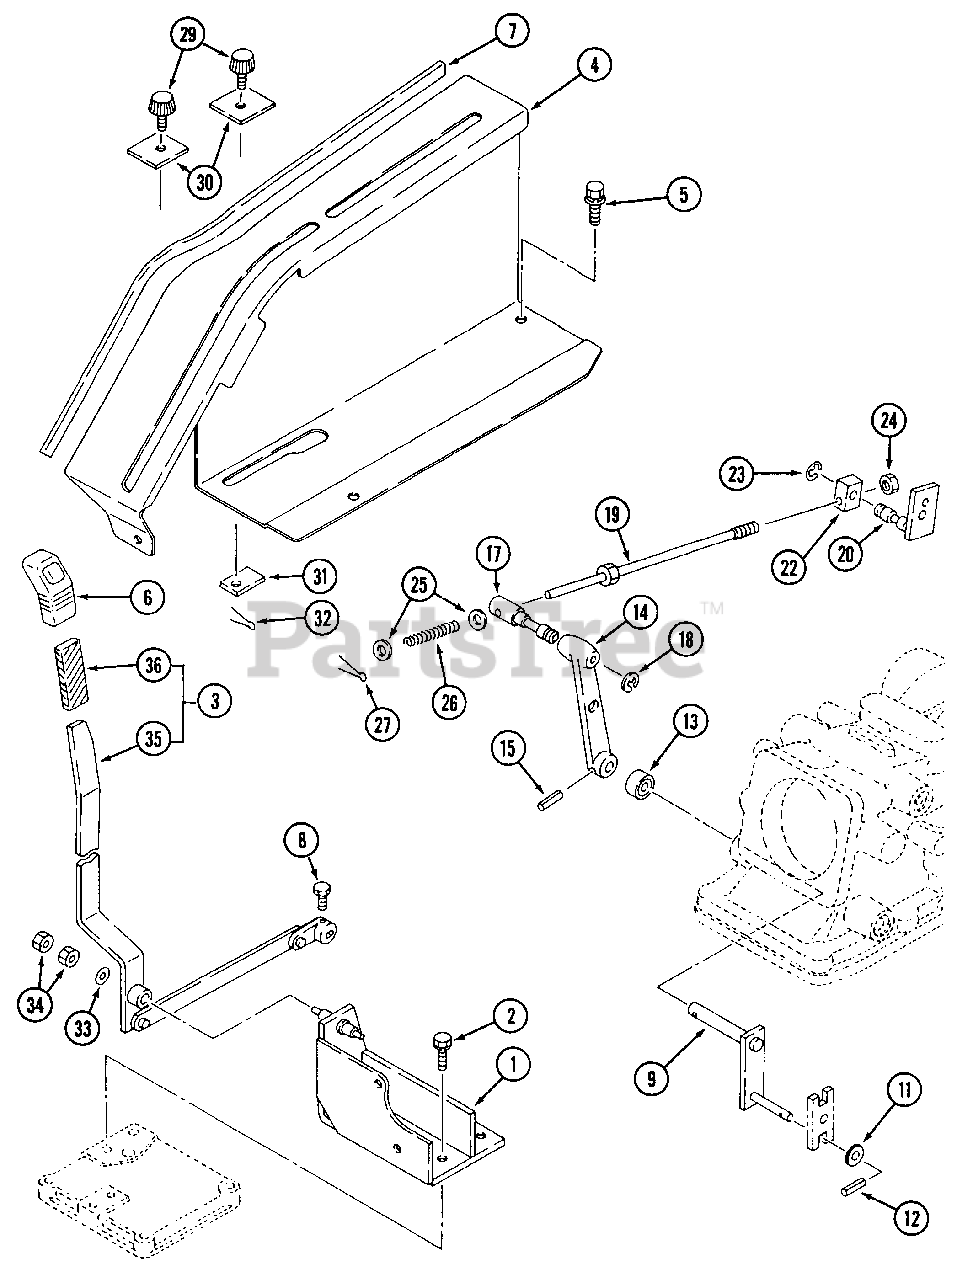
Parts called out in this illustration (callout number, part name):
3	Lever, P/C Ass'y.
4	Lever Guide R.H.
14	Arm, Feedback
22	Joint
27	Pin, Split
35	Lever, P/C Ass'y.
